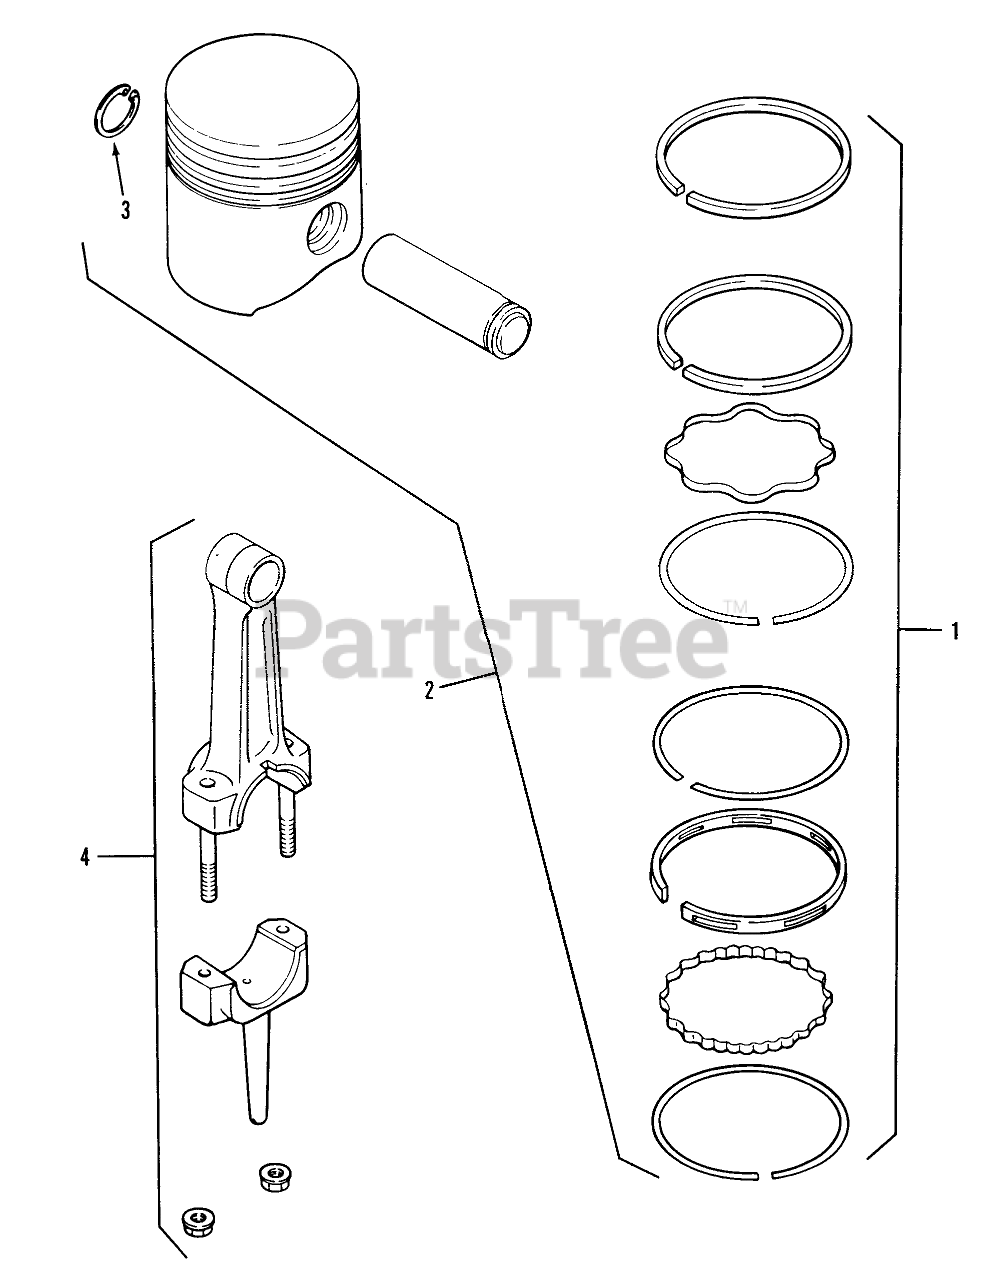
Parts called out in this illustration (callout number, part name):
1	Ring set-Std. & .003 (Svc.)
2	Piston wiring Set Std. 312
3	Retainer-Piston Pin
4	Connecting Rod Std. 312
